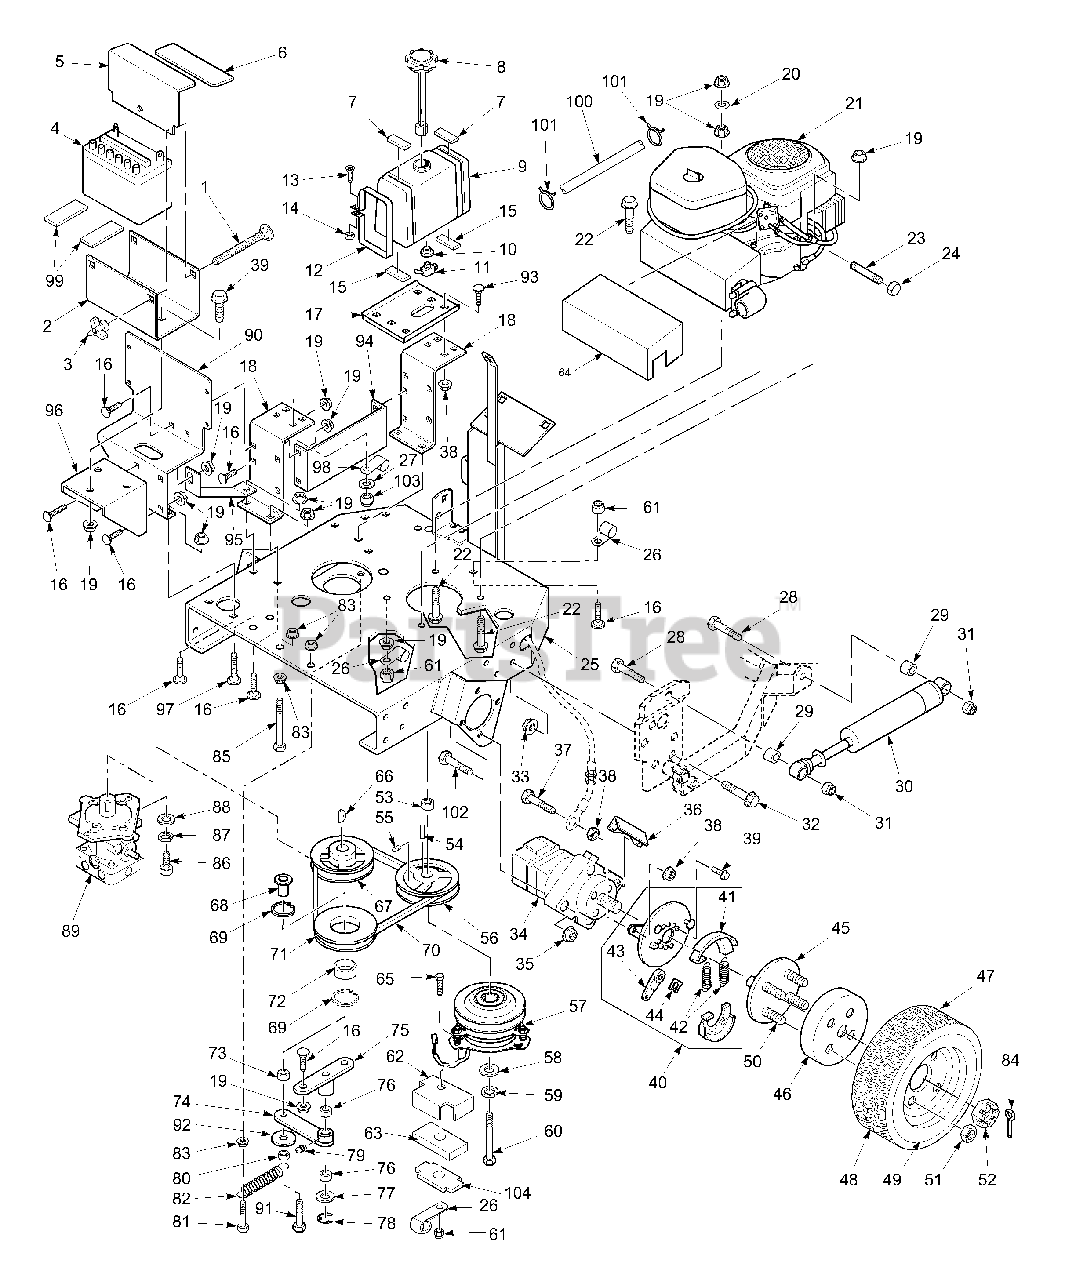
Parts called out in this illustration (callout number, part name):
1	Carriage Bolt, 1/4-20 x 6"
2	Battery Box
3	Nut, Wing 1/4-20
4	Battery
5	Battery Cover
6	Insulation, Battery Cover
7	Pad, Fuel Tank Strap
8	Cap, Fuel Tank
9	Fuel Tank Assy.
10	Bushing, Fuel Tank Valve
11	Fuel Shut Off Valve
12	Strap, Fuel Tank
13	Phil RDHD Machine Screw 1/4-20 x 2"
14	Hex Nut, 1/4-20
15	Pad, Fuel Tank Support
16	Carriage Bolt, 5/16-18 x 3/4"
17	Support, Fuel Tank
18	Bracket, Fuel Tank Support
19	Serr. Fl. Hex Nut 5/16-18
20	Lockwasher, 5/16 Int. Tooth
21	Engine, 23 HP Kohler CV, (Spec PS-75523)
22	Hex Head CPSCR, 5/16-18 x 1-3/4"
23	Oil Drain Extension
24	Cap, Oil Drain Plug
25	Engine Deck
26	Wire Loom, .50 I.D.
27	Washer, 1/4 (.312 x .750 x .065)
28	Bolt, Hex Head 1/2-13 x 2"
29	Sleeve, Shock Absorber Mount
30	Shock Absorber
31	Hex Locknut, Elastic Stop 1/2-13
32	Serr. Fl. Hex Head CPSCR, 7/16-14 x 1"
33	Serr. Fl. Hex Nut, 7/16-14
34	Motor - White
35	Lockwasher, 1/2"
36	Anchor, Brake
37	Bolt, Hex Head 1/4-20 x 1-1/4"
38	Serr. Fl. Hex Nut, 1/4-20
39	Serr. Fl. Hex Head CPSCR, 5/16-18 x .75"
40	Parking Brake Assembly
41	Brake Pads - Pair
42	Springs - Pair
43	Actuating Arm,
45	Hub Assembly
46	Brake Drum
47	Rim and Tire Assembly
48	Tire 20 x 10 x 10, 4 Ply
49	Rim Only
50	Bolt, Hub
51	Wheel Nut
52	Castle Nut, 1.0-20 UNEF
53	Spacer, Clutch
54	Key, 1/4 x 1/4 x 1-1/2"
55	Hex Socket Set Screw, 5/16-18 x 3/8"
56	Pulley, Engine Pump Drive
57	Clutch, Electric (Ogura)
58	Flatwasher, 7/16 (.469 x 1.75 x .25)
59	Lockwasher, 7/16"
60	Bolt, Hex Head 7/16-20 x 2.75"
61	Hex Locknut, Elastic Stop 5/16-18
62	Backing Plate, Clutch Stop
63	Rubber Pad, Clutch Stop
64	Heatshield, Muffler
65	Bolt, Hex Head 5/16-18 x 1-3/4"
66	Key, Woodruff 3/16 x 5/8"
67	Pulley, Pump Input
68	Sleeve, Idler
69	Ring, Retaining, 1-9/16 Internal
70	Belt, Pump Drive
71	Pulley, Idler-Traction Drive
72	Bearing, Idler Pulley
73	Spacer, Idler
74	Pump Idler Arm
75	Idler Pivot Base
76	Bushing, Oillube
77	Flatwasher, 3/4"
78	Ring, Retaining, 3/4" Ext. "E"
79	Grease Fitting
80	Hex Nut, Jam 3/8-16
81	Bolt, Hex Head 3/8-16 x 3-1/4"
82	Spring, Pump Drive Idler
83	Serr. Fl. Hex Nut, 3/8-16
84	Cotter Pin, 5/32 x 1.50"
85	Bolt, Hex Head 3/8-16 x 5"
86	Socket Head CPSCR, 1/2-13 x 1-1/4"
87	Lockwasher, 1/2"
88	Flatwasher, 1/2 (.516 x .938 x .105)
89	Pump, Sundstrand
90	Bracket, Oil Tank Support
91	Bolt, Hex Head 3/8-16 x 1-3/4"
92	Washer 2" OD, 3/8 ID, 16 Ga.
93	Carriage Bolt, 1/4-20 x 3/4"
94	Guard, Pulley
95	Gusset, Battery Box
96	Support, Battery Box
97	Carriage Bolt, 5/16-18 x 1"
98	Wire Loom, .75" I.D.
99	Rubber Pad
100	Fuel Hose, Order by the inch
101	Clamp, Fuel Hose
102	Bolt, 1/2-13 x 2.50"
103	Nut, 1/4-20 Elastic Stop
104	Plate, Backing
